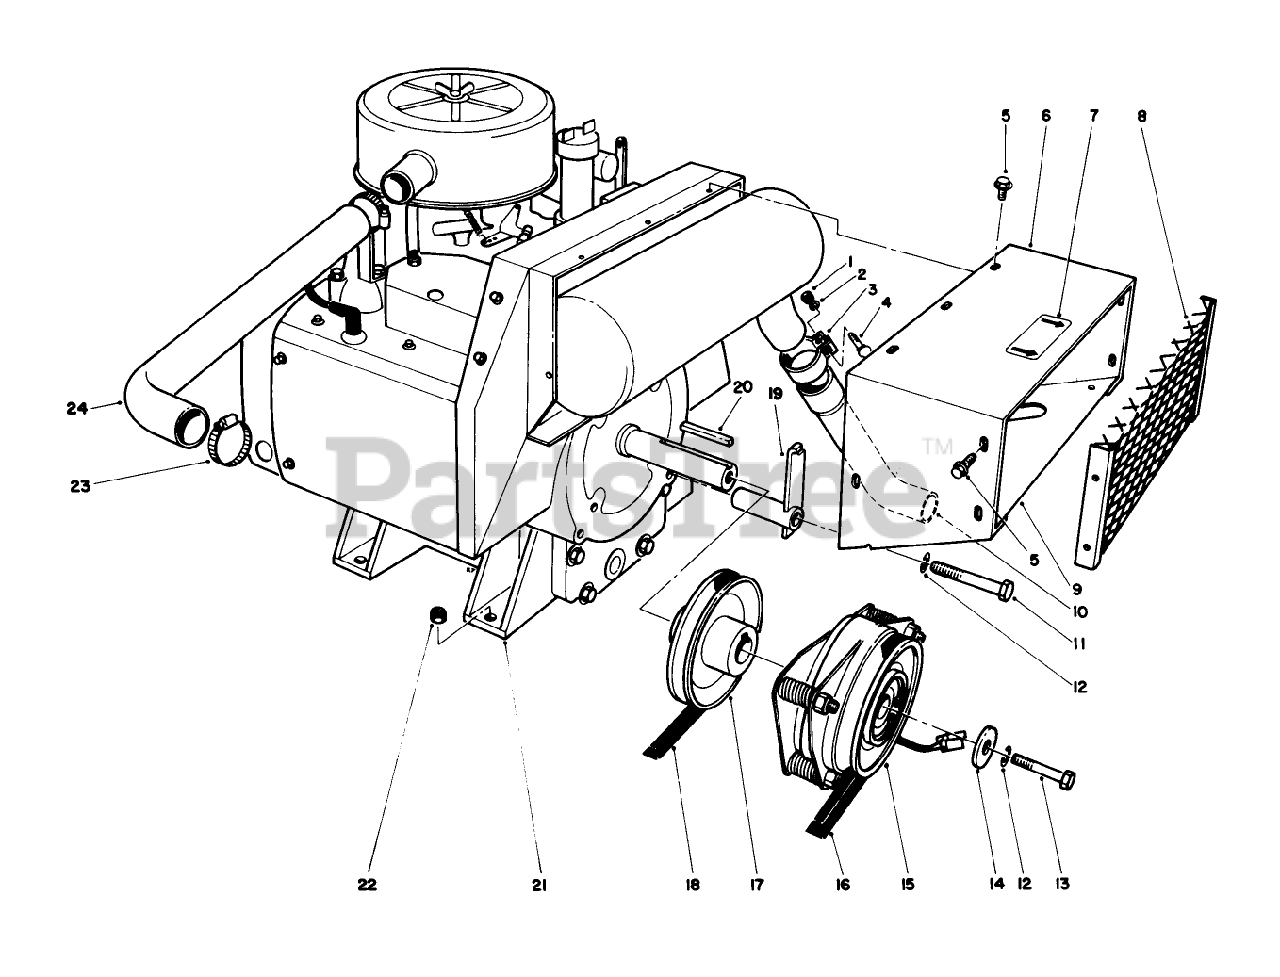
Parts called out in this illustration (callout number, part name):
1	NUT-HEX
2	WASHER-LOCK
4	SCREW-CARR
5	SCREW-HHFTF
6	ENGINE DUCT WA *B
11	SCREW-HH
12	WASHER-LOCK
13	SCREW-HH
15	BRAKE CLUTCH ASM
16	V-BELT, JACKSHAFT
17	ENGINE PULLEY
18	V-BELT, TRACTION
22	NUT-LOCK, NI
23	CLAMP-HOSE
